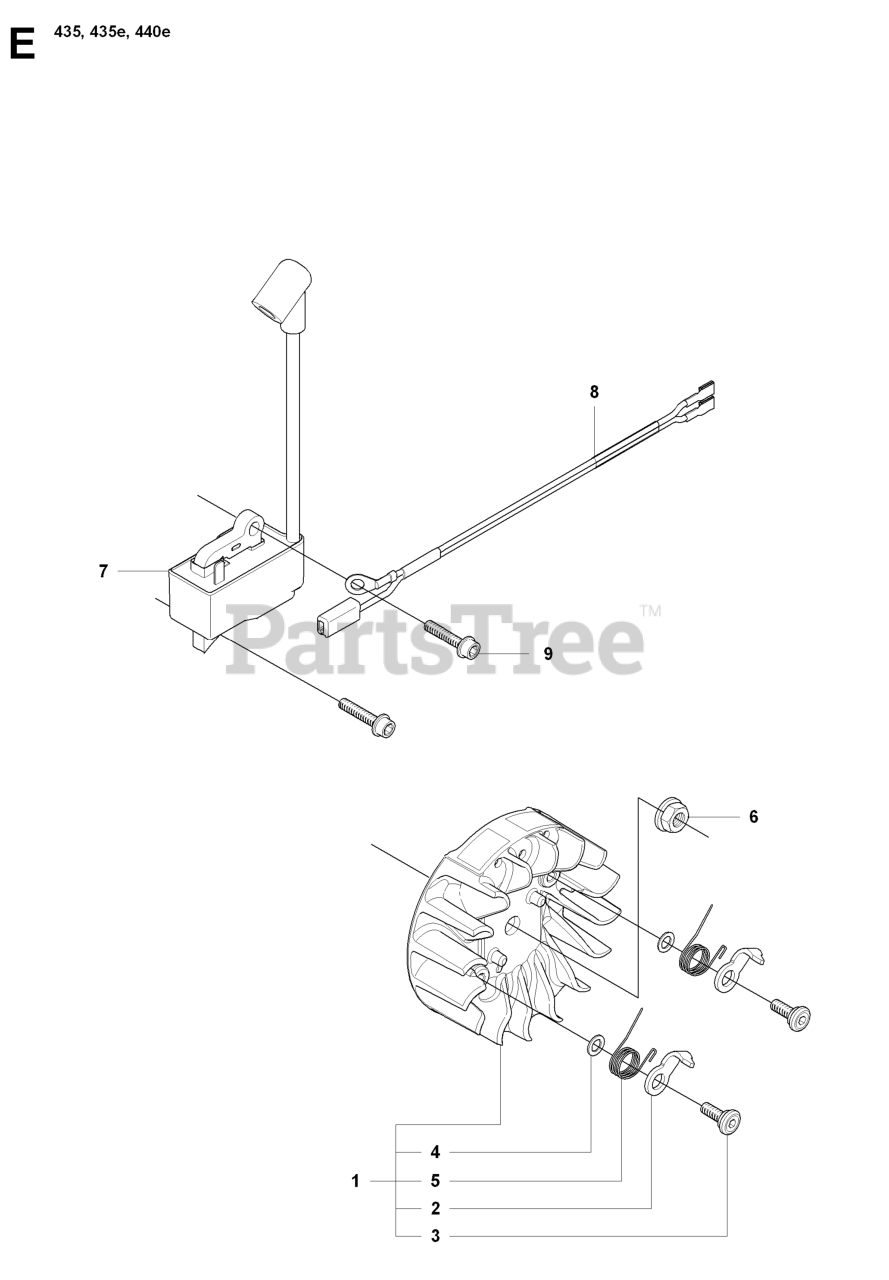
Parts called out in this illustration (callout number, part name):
1	%FLYWHEEL ASSY
5	%SPRING, STARTER CATCH
6	NUT W/ WASHER
7	%IGNITION MODULE
8	WIRING ASSY
